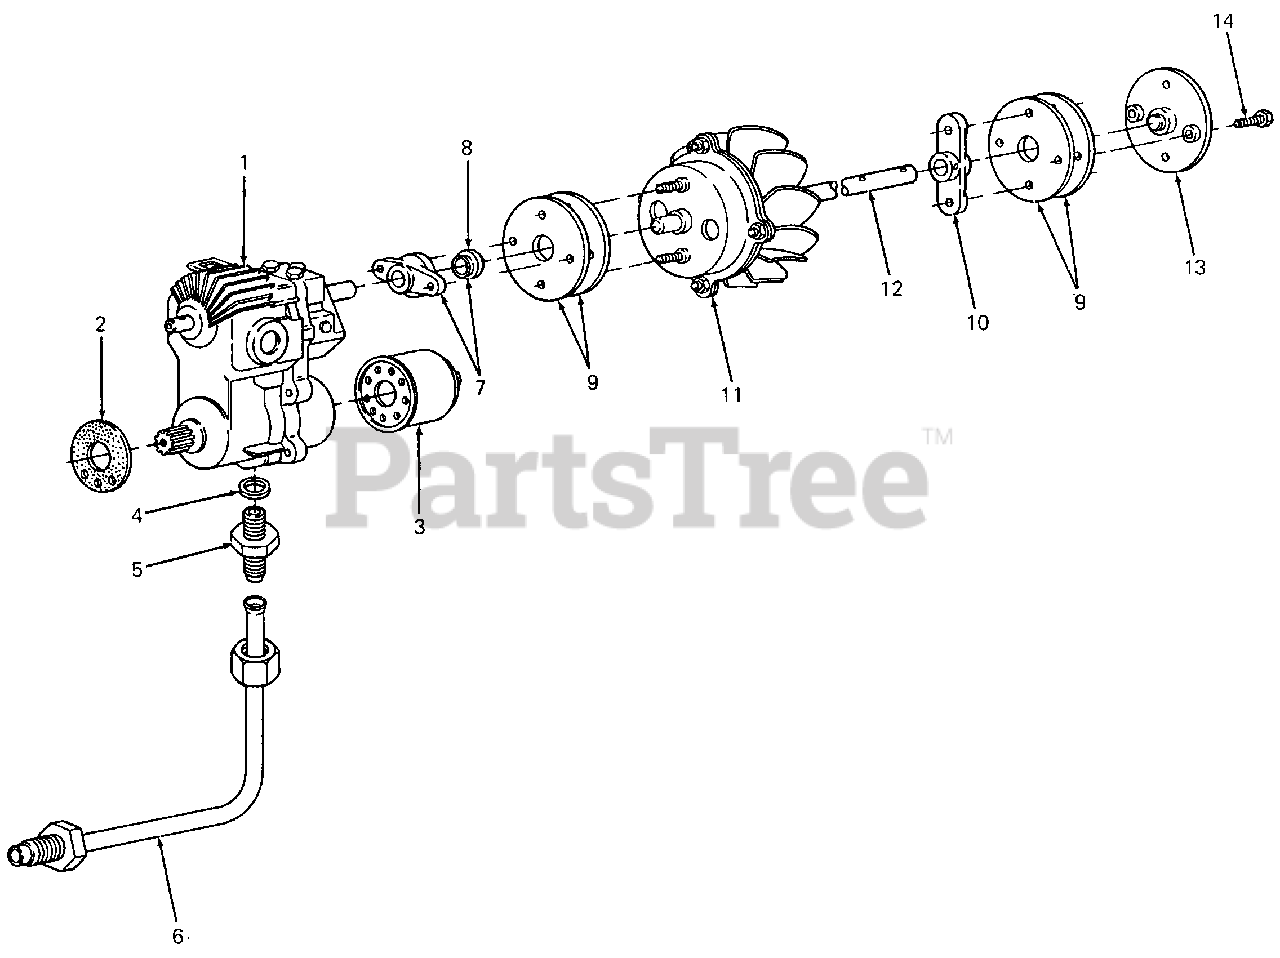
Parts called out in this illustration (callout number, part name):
1	Pump, Hydrostatic
2	Gasket, Front
3	Filter, Oil
4	O-Ring, 5/8 OD Tube
5	Connector, 37 Degree
6	Tube Assy
7	Coupling Assy
8	Bushing, Ball
9	Disc, Flexible
10	Arm, Coupling
11	Clutch Assy, Drive Shaft
12	Shaft, Drive
13	Bearing Assy, Engine Coupler
14	Screw, Hex Cap, 3/8-16 X 1.75 Lg GR5
